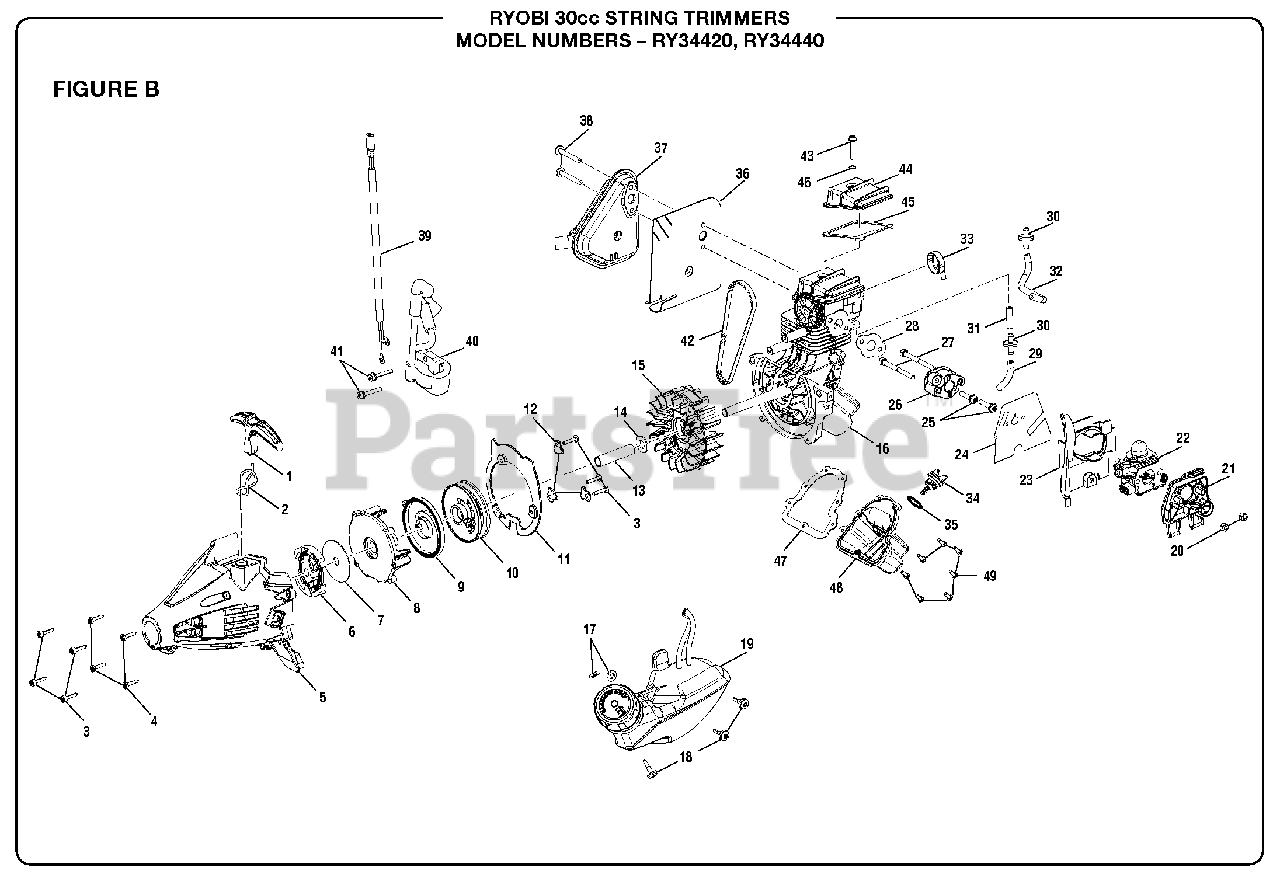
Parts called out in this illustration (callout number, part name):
1	Starter Grip
2	Starter Rope
3	Screw (M4 x 18 mm)
4	Screw (M4 x 16 mm)
5	Starter Housing Assembly
6	Clutch Assembly
8	Starter Baffle
9	Spring & Container
10	Easy Starter Assembly
12	Pulley Retainer
13	Spacer Tube
14	Washer
15	Flywheel Assembly
16	Short Block Assembly
18	Screw (M4)
19	Fuel Tank & Cap Assembly
20	Nut (M5 x 0.8)
21	Air Filter Base
22	Carburetor Assembly
23	Air Baffle
24	Carburetor Gasket
25	Screw (M5 x 23 mm)
28	Heat Dam Gasket
29	Breather Hose
30	Check Valve
31	Breather Hose
32	Breather Hose
33	Breather Fitting
34	Oil Cap/Dipstick
36	Muffler Gasket
37	Muffler Assembly
38	Muffler Bolt (M5 x 42 mm)
39	Electrical Lead Wire Assembly
40	Ignition Module
41	Screw (M4 x 19 mm)
42	Timing Belt
43	Screw (M4 x 27 mm total, 14 mm threaded)
44	Cam Cover
49	Screw (M4 x 12 mm)
